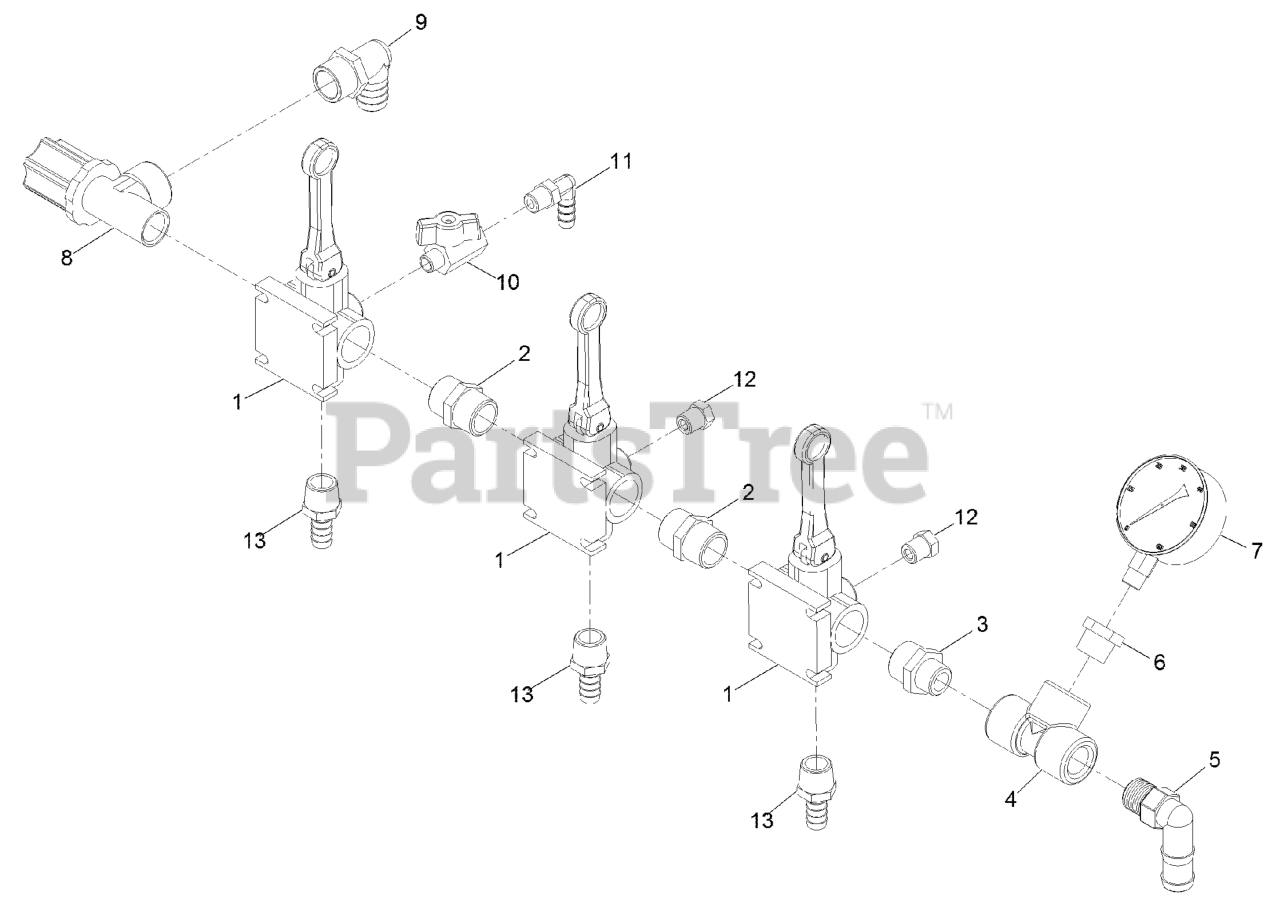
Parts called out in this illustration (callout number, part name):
1	VALVE-DIRECTO
2	FITTING-NIPPLE
3	FITTING-NIPPLE
5	ELBOW-90
6	FITTING-REDUCER
7	GAUGE
8	VALVE-THROTTLE
9	FITTING-ELBOW, 90
10	VALVE-CHROME, 1/4
11	FITTING-ELBOW, 90
12	PLUG-VALVE
13	FITTING-HOSEBARB
